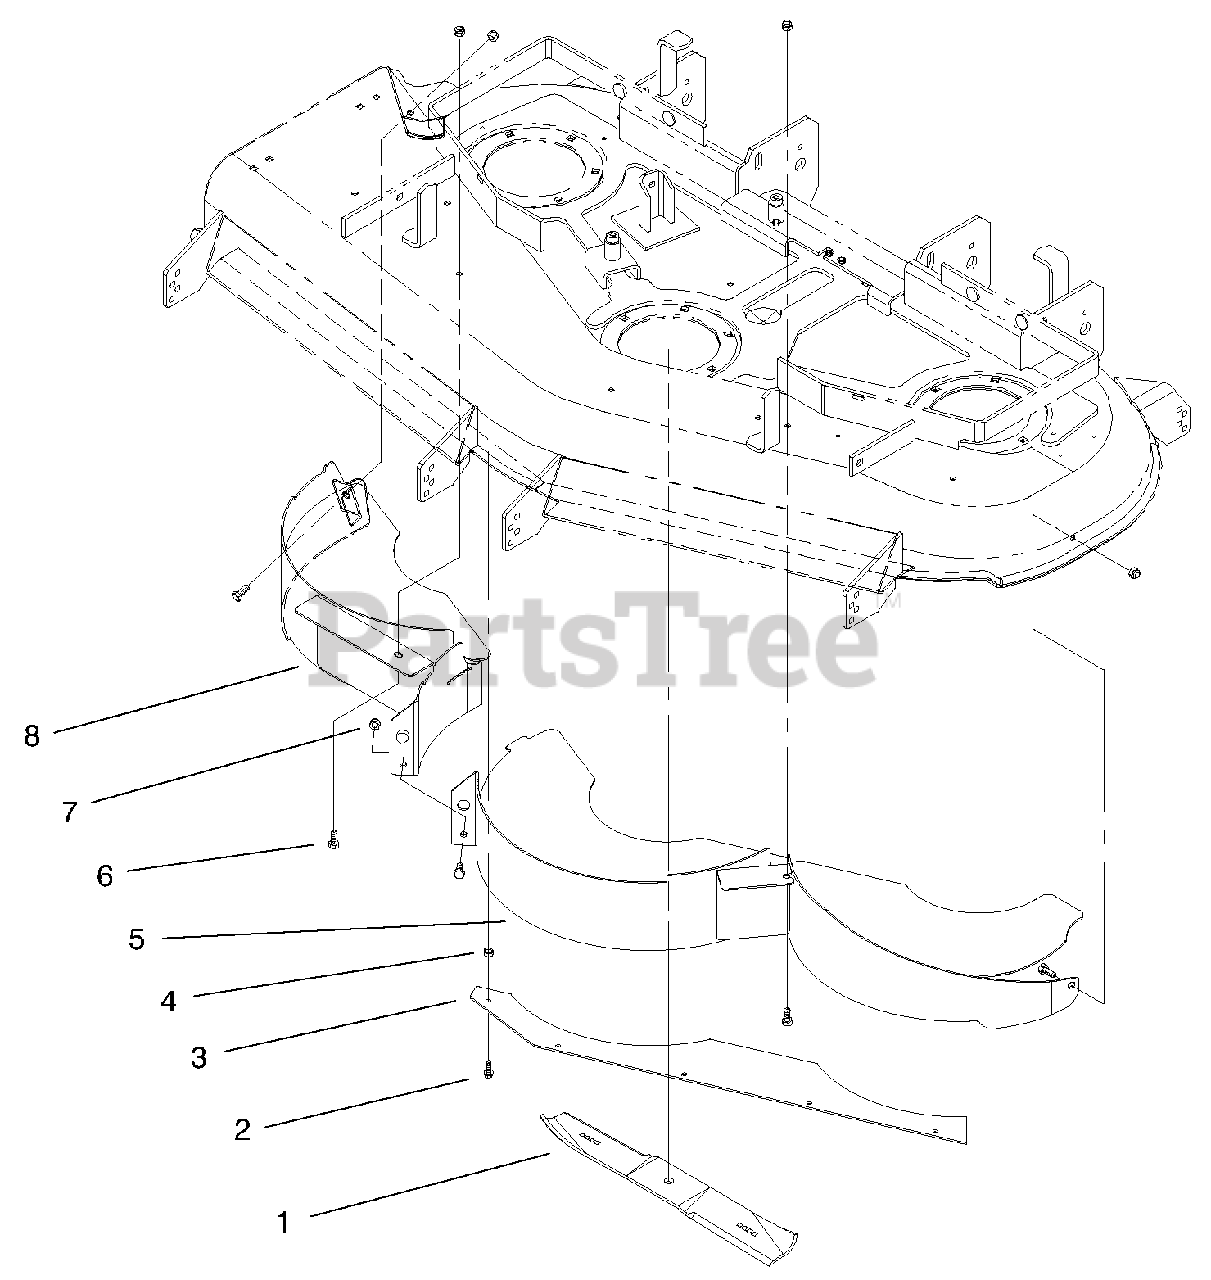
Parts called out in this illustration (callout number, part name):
1	Blade-Mulch
2	Screw-Taptite
3	Baffle-Blowout
5	Baffle-Left
6	Screw-HH
7	Nut-Lock
8	Baffle-Right
